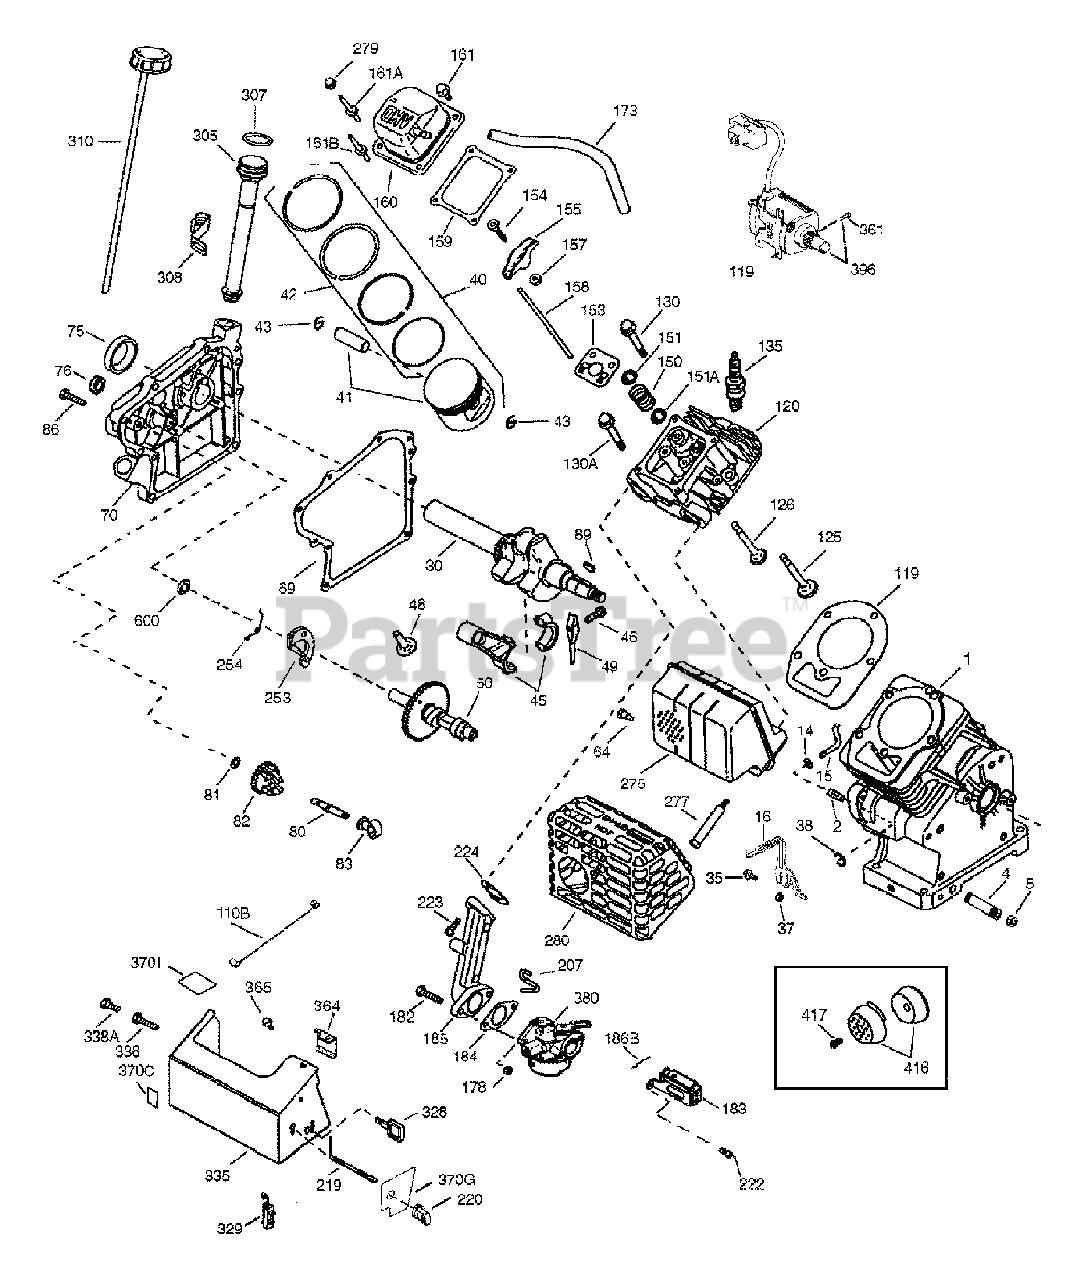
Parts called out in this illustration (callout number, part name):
1	Cylinder
2	Dowel Pin
4	Oil Drain Extension
5	Extension Cap
15	Governor Rod
16	Governor Lever
30	Crankshaft
35	Screw, 10-32 x 63/64"
37	Lock Nut, 10-32
38	Retaining Ring
40	Piston, Pin & Ring Set (Std.)
40	Piston, Pin & Ring Set (.010" OS)
41	Piston & Pin Ass'y (Std.)
41	Piston & Pin Ass'y (.010" OS)
42	Ring Set (Std.)
42	Ring Set (.010" OS)
43	Piston Pin Retaining Ring
45	Connecting Rod Ass'y
46	Connecting Rod Bolt
48	Valve Lifter
49	Oil Dipper
50	Camshaft
64	Screw, 1/4-20 x 27/32"
69	Cylinder Cover Gasket
70	Cylinder Cover
76	Camshaft Seal
80	Governor Shaft
82	Governor Gear Ass'y
83	Governor Spool
86	Screw, 1/4-20 x 1-1/4"
89	Flywheel Key
110B	Ground Wire
119	Cylinder Head Gasket
120	Cylinder Head
125	Exhaust Valve (Std.)
125	Exhaust Valve (1/32" OS)
126	Intake Valve (Std.)
130	Screw, 5/16-18 x 1-1/2"
130A	Screw, 5/16-18 x 2-41/64"
135	Resistor Spark Plug (RN4C)
150	Valve Spring
151	Valve Spring Cap
151A	Intake Valve Seal
153	Push Rod Guide
154	Rocker Arm Stud
155	Rocker Arm
157	Nut, 1/4-28
159	Rocker Arm Cover Gasket
160	Rocker Arm Cover
161	Screw, 1/4-20 x 31/64"
173	Breather Tube
178	Nut, 1/4-20
182	Screw, 1/4-20 x 1"
183	Choke Bracket
184	Carburetor To Intake Pipe Gasket
185	Intake Pipe
186B	Choke Spring
207	Throttle Link
219	Choke Rod
220	Choke Knob
222	Screw, 10-32 x 1/2"
223	Screw, 1/4-20 x 1"
224	Intake Pipe Gasket
253	Compression Release Weight
254	Compression Release Spring
275	Muffler
277	Screw, 1/4-20 x 2-9/32"
279	Nut & Lock Washer
280	Heat Shield
305	Oil Fill Tube
308	Fill Tube Clip
328	Ignition Key
335	Carburetor Cover
338	Screw, 10-32 x 1/2"
338A	Screw, 10-32 x 3/8"
361	Screw, T-30, 1/4-20 x 15/32"
364	Carburetor Cover Bracket
365	Screw, 10-32 x 1/2"
370C	Primer Decal
370G	Instruction Decal
370I	Warning Decal
380	Carburetor
396	Electric Starter Motor (110 Volt)
416	Spark Arrestor Kit
417	Screw, 10-32 x 1/2"
